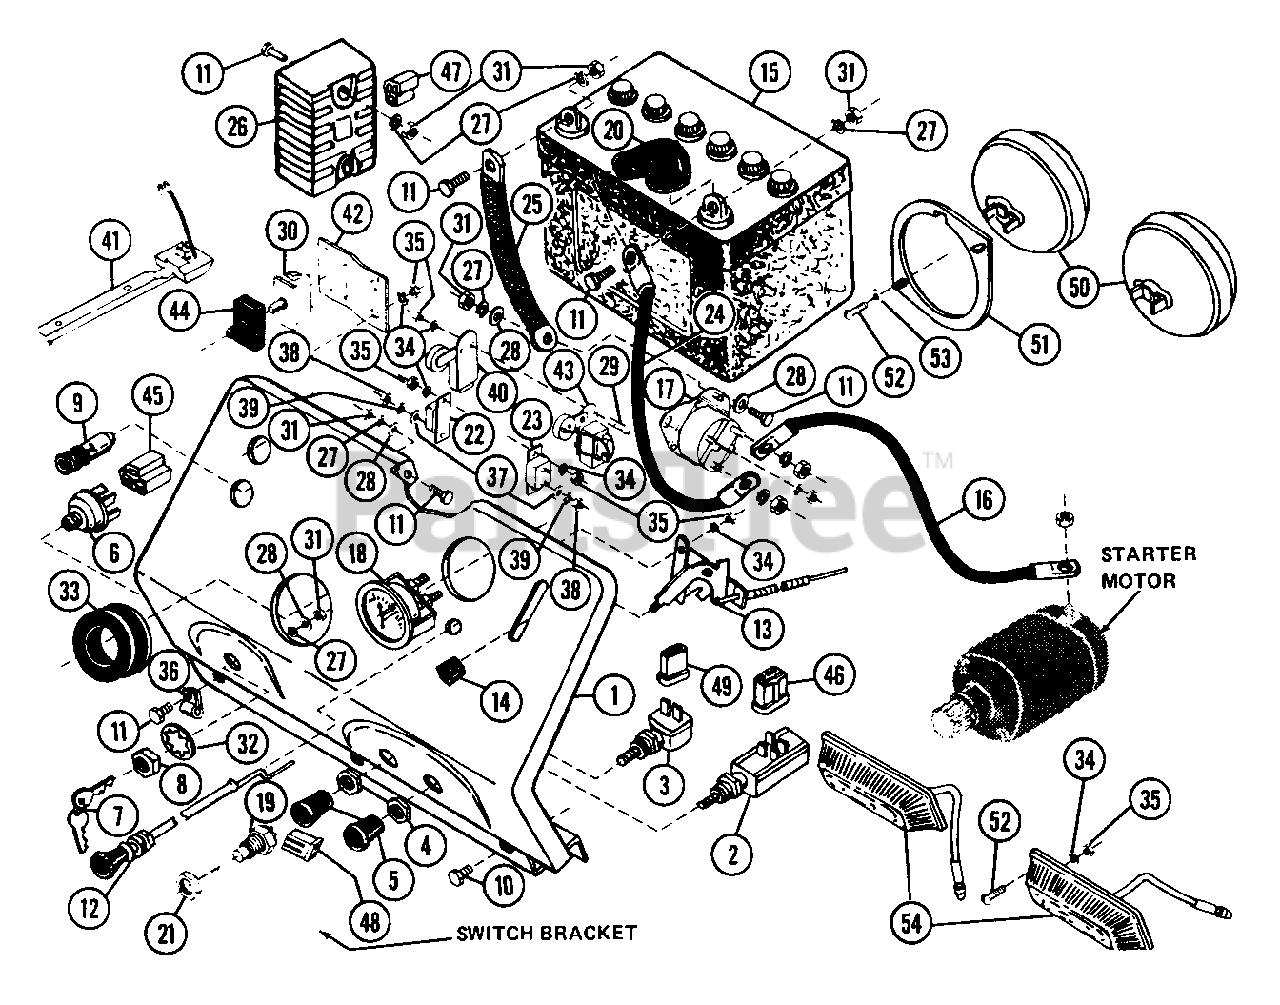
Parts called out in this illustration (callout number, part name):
1	DASH ASSEMBLY
2	CLUTCH SWITCH
3	LIGHT SWITCH
4	NUT .50-20 PL
6	IGNITION SWITCH
7	KEYS
8	NUT .562-24
9	P.T.O. INDICATOR & WIRE
10	SCR-TAP 10-16X.50 HWH PL AB
11	BLT-HEX .25-20X.75 PL GR2
12	CHOKE CONTROL
13	THROTTLE CONTROL
15	BATTERY
16	GROUND CABLE .31X22.00X.31
17	SOLENOID
18	AMMETER
19	SWITCH-NEUTRAL START N.O.
20	INSULATOR
21	NUT- .562-18
22	CIRCUIT BREAKER
23	CIRCUIT BREAKER
25	GROUND CABLE
26	REGULATOR RECTIFIER
27	WSHR-LK .250X.077 HVY PL
28	WSHR-FL-STL.281X.62X.065 PL
29	SCR-MCH 10-24X.50 SLRH PL
31	NUT-HEX .250-20 PL
32	WSHR-LK-INT .563X.040 PL
33	GROMMET
34	WSHR-LK 10X.047 MED PL
35	NUT-HEX 10-24 PL
37	WSHR-FL-STL .219X.500X.049 PL
38	NUT 10-32 PL
39	WSHR-LK 10X.047 MED PL
40	RELAY - DIODE
41	SWITCH SEAT
42	SWITCH BRACKET
43	CLUTCH CONTROL RELAY
44	SWITCH BOOT
45	CONNECTOR HOUSING
46	CONNECTOR
47	CONNECTOR
48	CONNECTOR
49	CONNECTOR
50	HEAD LIGHT
51	HEAD LIGHT RETAINER RING
52	SCR-MCH 10-24X.50 SLTR PL
53	WSHR-FL-STL .250X.562X.049 PL
54	TAIL LIGHT
